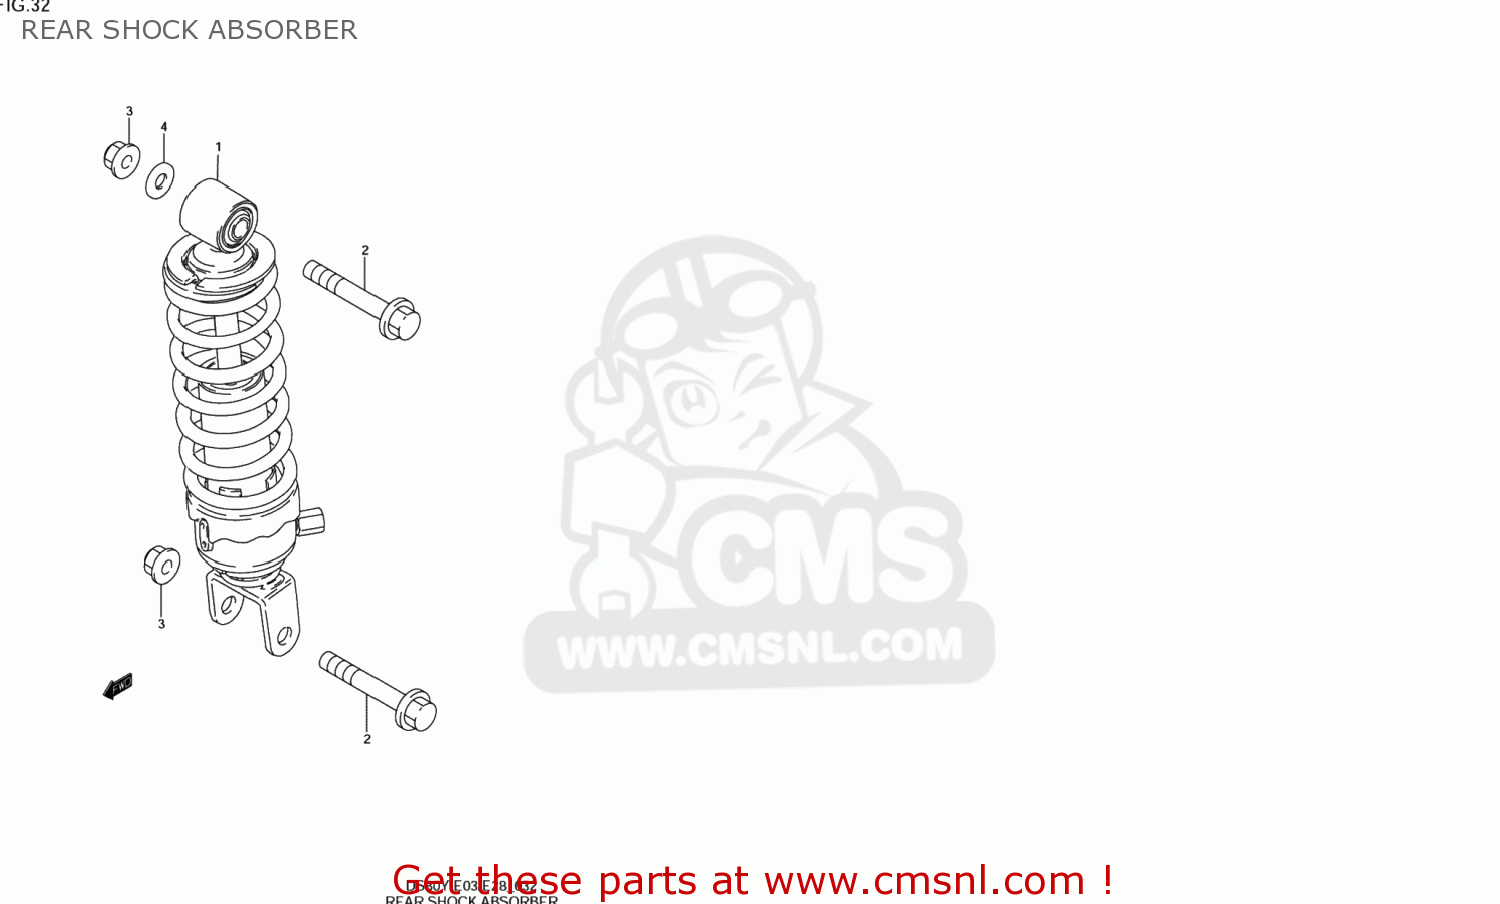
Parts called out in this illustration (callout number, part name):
1	ABSORBER ASSY,RR SHOCK
2	BOLT,RR SHOCK ABSORBER(10X51)
3	NUT
4	WASHER(10.5X22X1.6)
